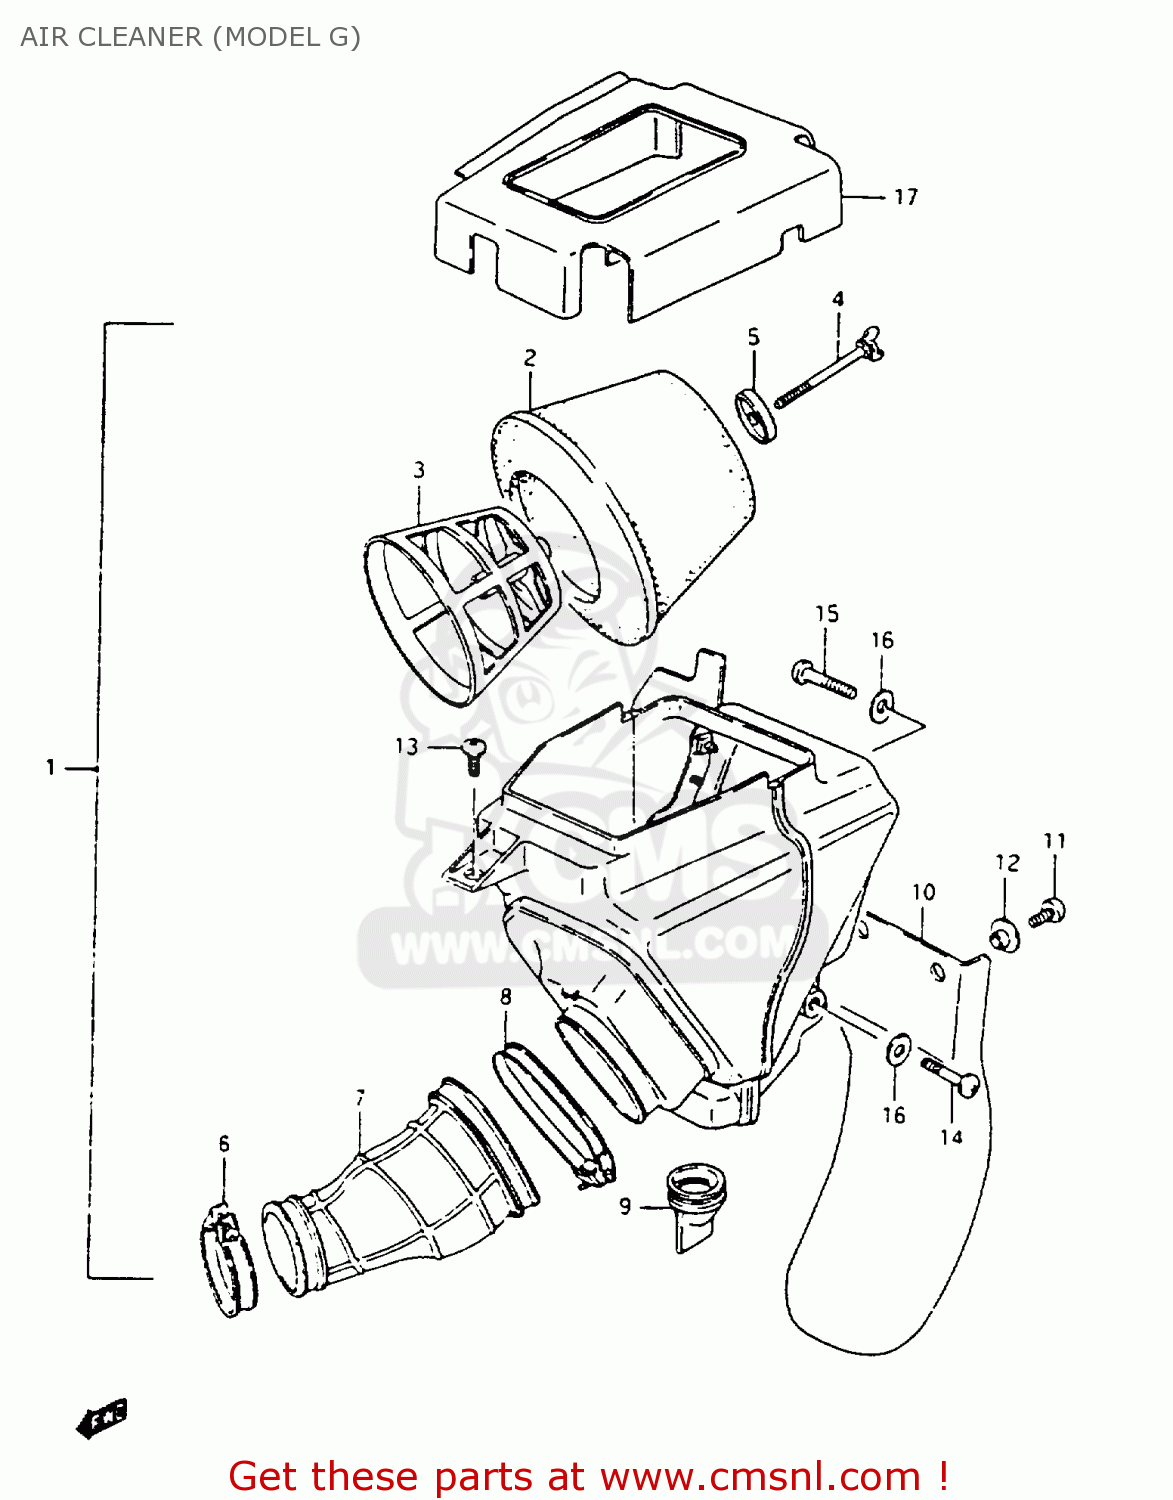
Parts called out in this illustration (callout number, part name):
1	CLEANER ASSEMBLY,AIR
2	FILTER ASSY
3	HOLDER
4	BOLT,WING
5	WASHER,AIR CLEANER
6	CLAMP
7	TUBE,AIR CLEANER OUTLET
8	CLAMP
9	HOSE,AIR CLEANER DRAIN
10	GUARD,MUD
11	SCREW
12	COLLAR
13	SCREW 6X12
14	SCREW
15	SCREW
16	WASHER
17	MUD GUARD,B
